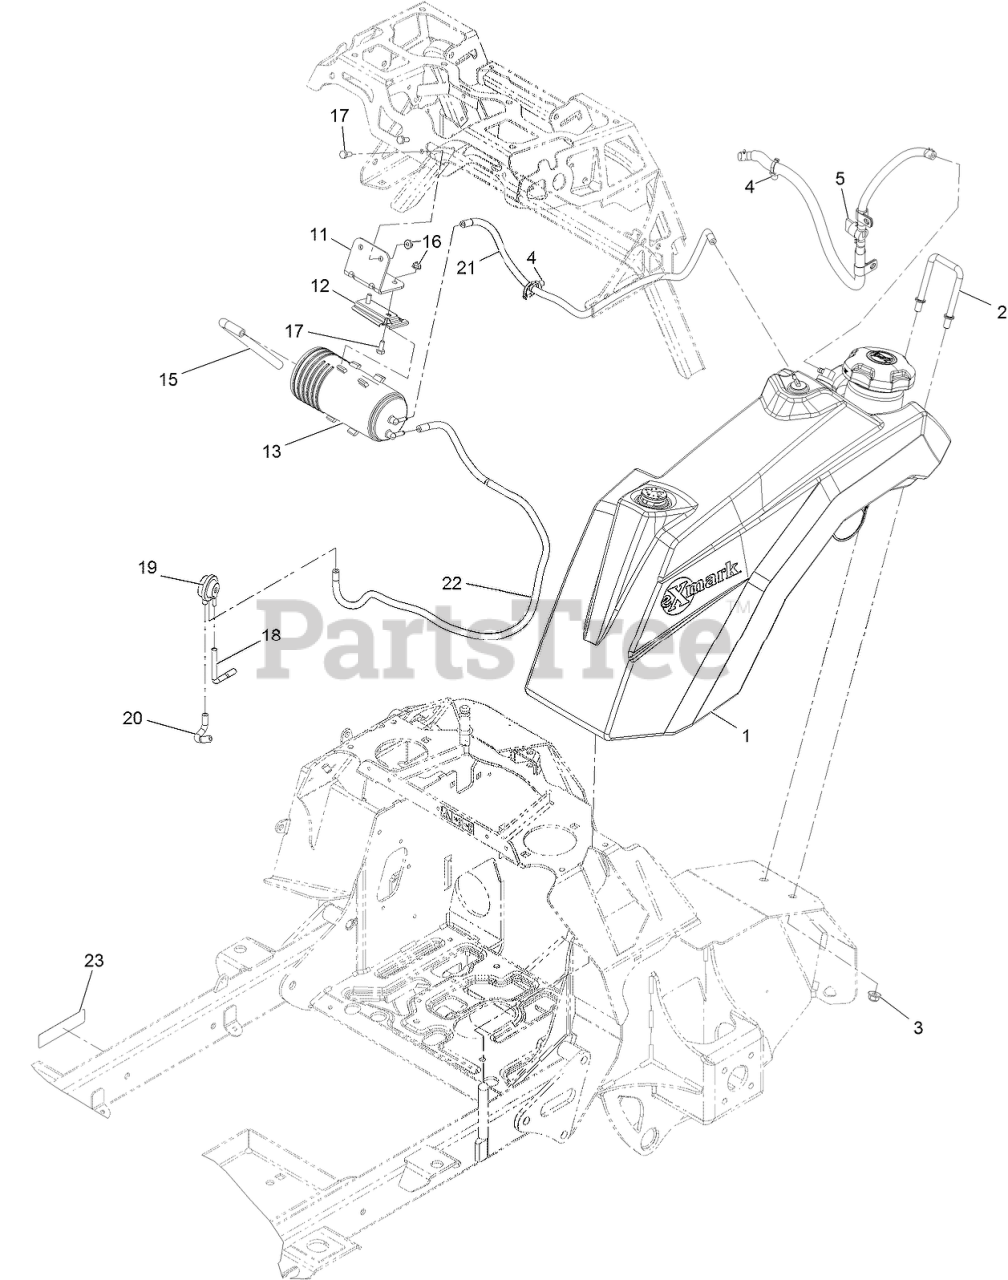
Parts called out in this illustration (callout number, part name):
1	ASSEMBLY, FUEL TANK
2	CLAMP, TANK
3	NUT-HF, NI
4	CLIP-TIE
5	ASM-FUEL LINE & VALVE
11	Bracket-Carbon Canister
12	BRACKET-CANISTER, CARBON
13	CANISTER-CARBON, 800CC
15	HOSE-VENT, CANISTER
17	SCREW-HH
18	HOSE-VENT, FORMED
19	VALVE-CONTROL, VACUUM
20	HOSE-VENT, FORMED
21	HOSE-FUEL
22	HOSE-FUEL
23	DECAL-ARRESTOR, SPARK
